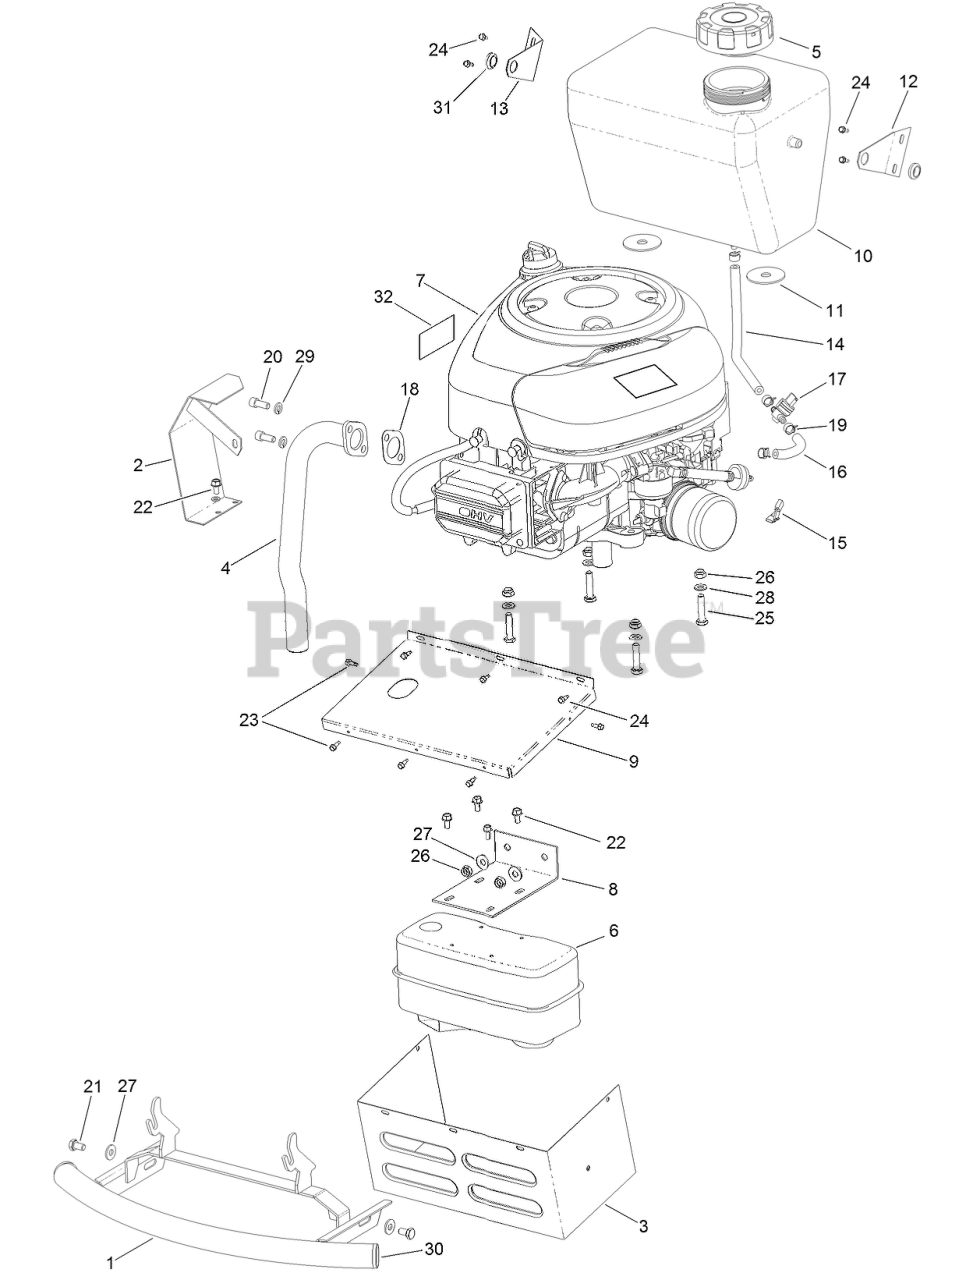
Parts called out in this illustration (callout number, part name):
1	BUMPER
2	SHIELD-EXHAUST TUBE
3	SHIELD-MUFFLER
4	TUBE-EXHAUST
5	CAP-FUEL
6	MUFFLER
8	BRACKET-MUFFLER MOUNT
9	COVER-TOP
10	TANK-FUEL
11	WASHER-RUBBER
12	BRACKET-FUEL TANK, LEFT
13	BRACKET-FUEL TANK, RIGHT
14	HOSE-FUEL
15	REDUCER-THROTTLE, RPM
16	LINE-FUEL
17	VALVE-TANK, FUEL
18	GASKET
19	CLAMP-LINE, FUEL
20	SCREW-HH
21	SCREW-HH
22	SCREW-HH
24	SCREW-TAP
25	SCREW
26	NUT-LOCK, NI
27	WASHER-PLAIN
28	WASHER-PLAIN
29	WASHER-SPRING
30	CAP-BUMPER
31	BUSHING
32	DECAL-DANGER, ENGINE
